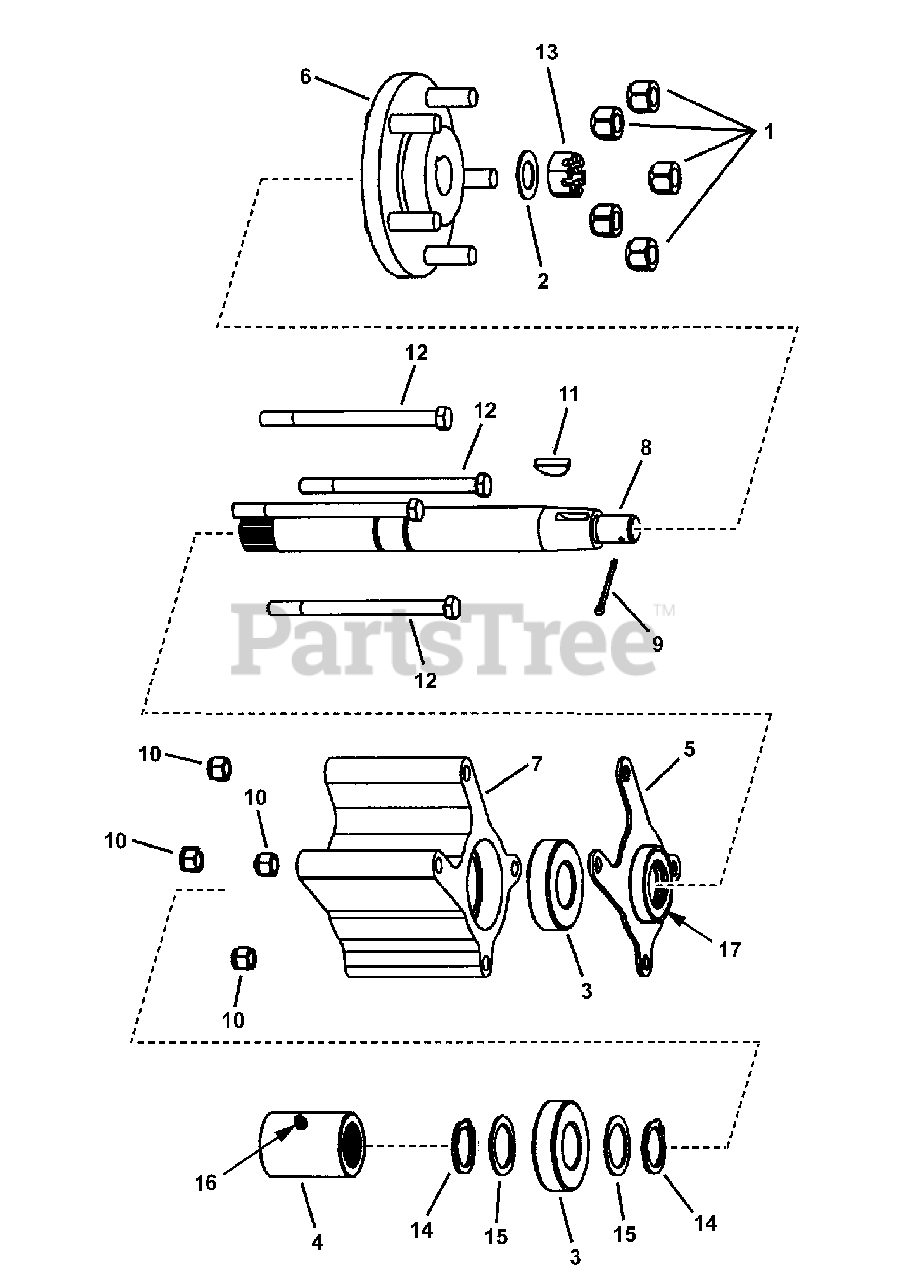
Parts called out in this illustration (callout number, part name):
1	LUG NUT, 1/2-20 Hex
2	WASHER, .77 x 1.5 x .06 Flat
3	BEARING, 30mm x 62mm
4	ASSEMBLY, Coupling w/Lube Fitting (Includes Ref. Nos. 16)
5	ASSEMBLY, Plate/Seal (Includes Ref. Nos. 17)
6	WHEEL HUB, Rear
7	AXLE SUPPORT, CVT, Aluminum
8	AXLE, CVT
9	COTTER PIN, 1/8 x 1-1/2
10	NUT, Hex Nyloc, 3/8-16
11	WOODRUFF KEY, #808
12	CAPSCREW, Hex Head, 3/8-16 x 5-1/2 GR 5
13	NUT, Slotted Hex, 3/4-16
14	SNAP RING, 30mm
15	WASHER, 1-3/16 x 1-5/8 x .06 Flat
16	FITTING, Lube 3/16
17	SEAL, 1.181 ID 1.850 OD
